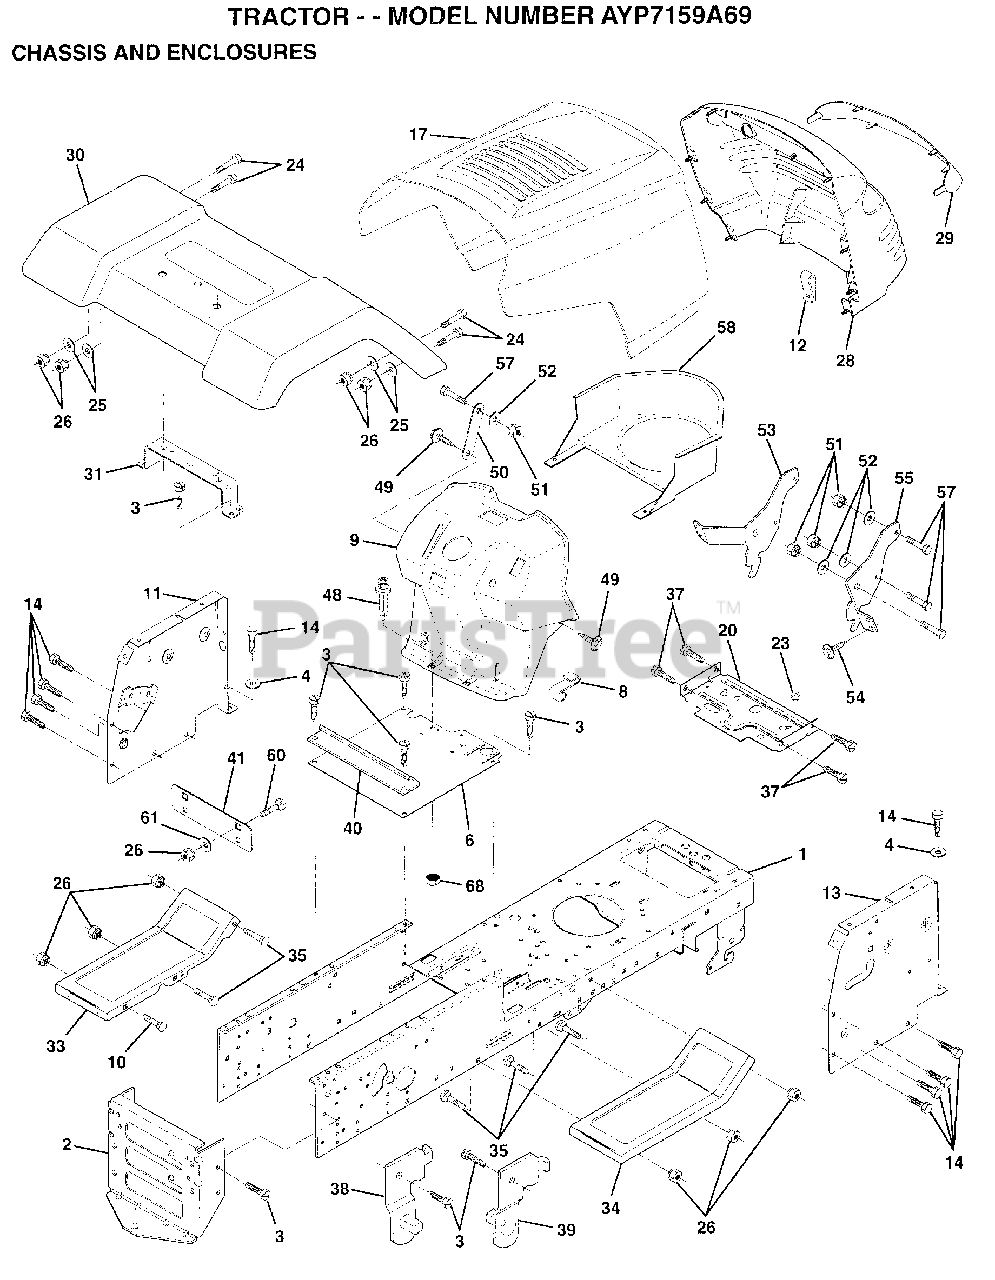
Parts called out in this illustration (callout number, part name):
1	CHASSIS.WLD.11GA
3	SCREW
4	WASHER
8	"CLIP,INSULATOR"
11	PANEL.DASH.LH.A
12	CLIP.TINNERMAN
13	PANEL.DASH.LH.
14	SCREW LT
17	HOOD.STL.PRV.LB
20	PLATE.MTG.BTRY.TK
24	BOLT
25	WASHER
26	NUT
28	GRILL.P/L.EURO.
29	LENS.EURO.W/DECAL
30	FENDER.PNT.LT.
31	BRACKET SUPT FEND
33	FOOTREST.LT.LT/GT
34	FOOTREST.RH.LT/GT
35	BOLT
37	SCREW LT
38	BRACKET ASM LH
39	BRACKET ASM RH
40	SPACER FENDER LT
41	PLATE EXTEN FEND
43	WASHER
48	RIVET.PUSH.PLATE
49	SCREW HEX CRT
50	BRACE SUPT DASH
51	NUT
52	WASHER
53	BRACKET.GRILLE.LH
55	BRACKET.GRILLE.RH
56	BOLT
58	AIR DUCT
68	NUT
